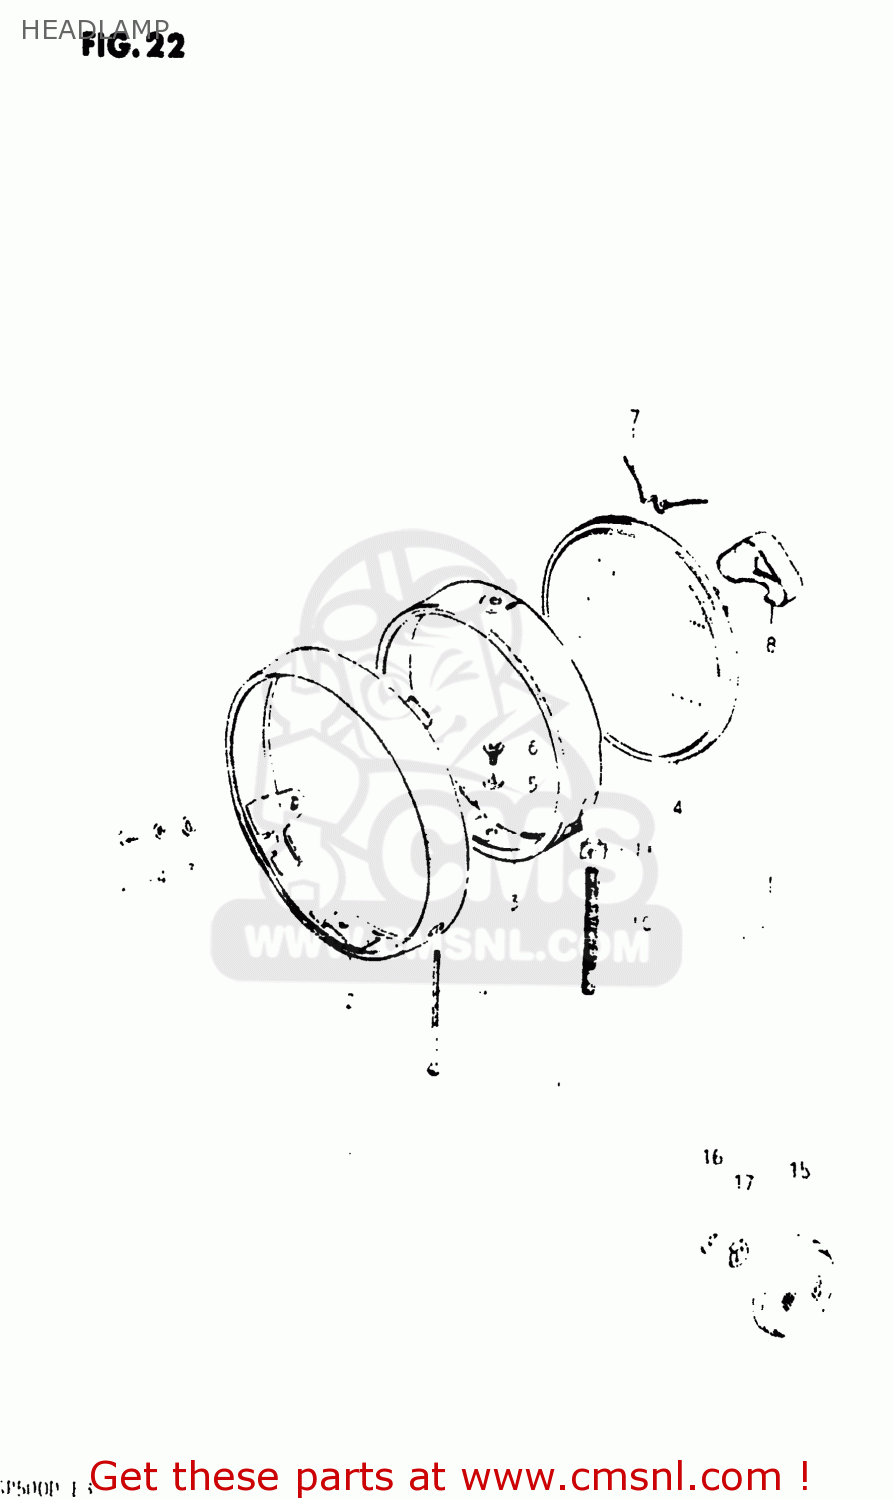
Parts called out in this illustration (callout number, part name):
1	HEADLAMP ASSEMBLY
2	RIM,HEADLAMP
3	RETAINER
4	LAMP UNIT
5	LOCK WASHER
6	SCREW
7	SPRING,HEAD LAMP UNIT
8	COVER
9	SCREW
10	SPRING
11	NUT
12	SCREW
13	WASHER
14	LOCK WASHER
15	REFLEX REFLECTOR,FR
16	WASHER
17	LOCK WASHER
